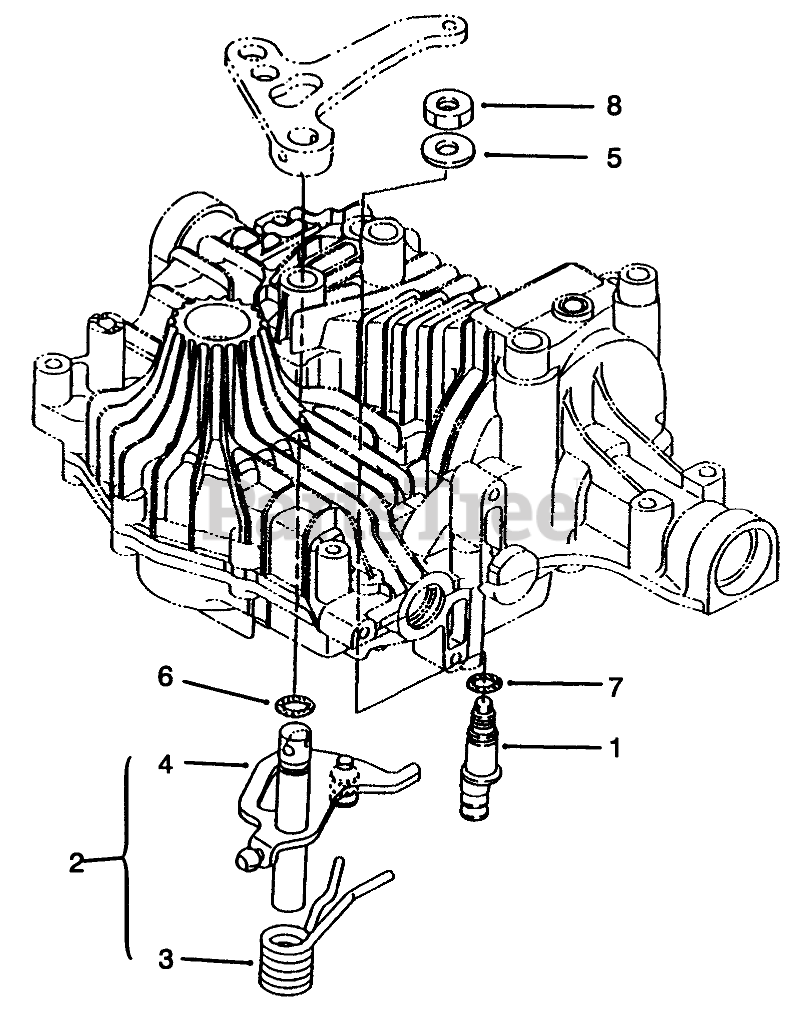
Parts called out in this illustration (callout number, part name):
1	FULCRUM
2	SHAFT ASM
4	Shaft-Control
5	WASHER
6	O-RING
7	PACKING
